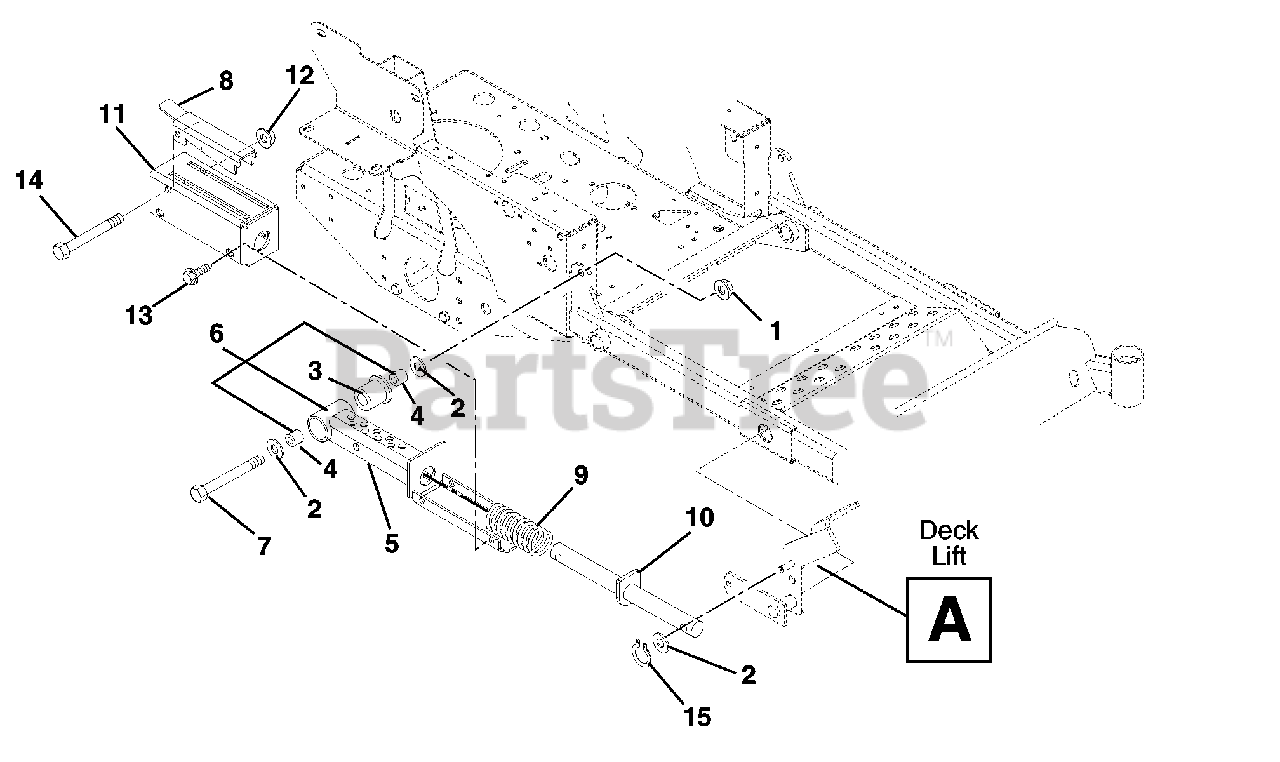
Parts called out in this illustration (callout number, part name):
1	Nut, Locking Top Flange .50-13
2	Washer, Flat Steel .531 x 1.25 x .10
3	Bearing, Pedestal Powdered Metal
4	Bearing, 1.00 x 1.12 x .75
5	Weldment, Mechanical Lift
6	Assembly, Mechanical Lift
7	Bolt, Hex .50-13 x 3.75 Grade 5
8	Lock-Up, Mechanical Lift
9	Spring, Compression 1.13 x 1.48 x 5.10
10	Weldment, Mechanical Lift Shaft
11	Weldment, Mechanical Lift Cover
12	Nut, Locking Top Flange .38-16
13	Screw, Tapping .38-16 x .50 Hex Washer Head
14	Bolt, Hex .38-16 x 3.25 Grade 5
15	Ring, Retaining External .50 x .05
